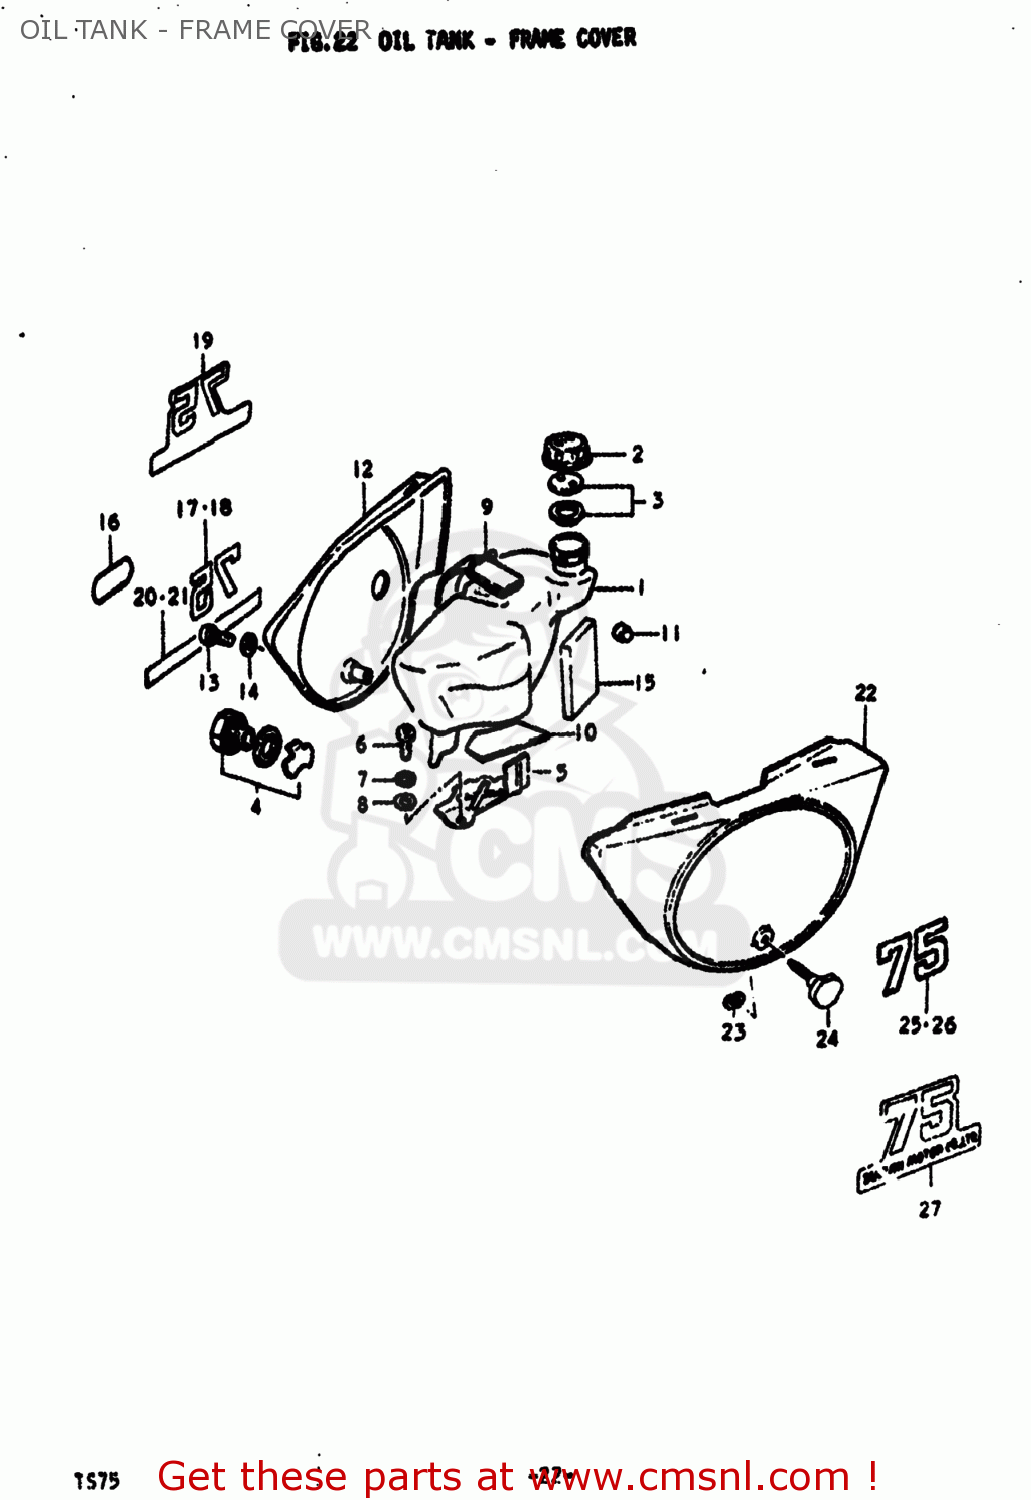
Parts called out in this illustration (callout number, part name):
1	TANK,OIL
2	CAP,OIL TANK
3	LENS,OIL LEVEL INSPECTION
4	LENS,OIL LEVEL INSPECTION
6	BOLT
7	LOCK WASHER
8	WASHER
9	BAND
10	CUSHION
11	CUSHION
12	COVER,FRAME,RIGHT
13	SCREW
14	WASHER
15	CUSHION 20X45X6
16	EMBLEM,CCIS
17	EMBLEM
18	EMBLEM
19	EMBLEM
20	LABEL,COMPANY NAME
21	LABEL (COMPANY NAME)
22	COVER,FRAME,LEFT
23	NUT (5MM)
24	KNOB,FRAME COVER
25	EMBLEM
26	EMBLEM
27	EMBLEM
